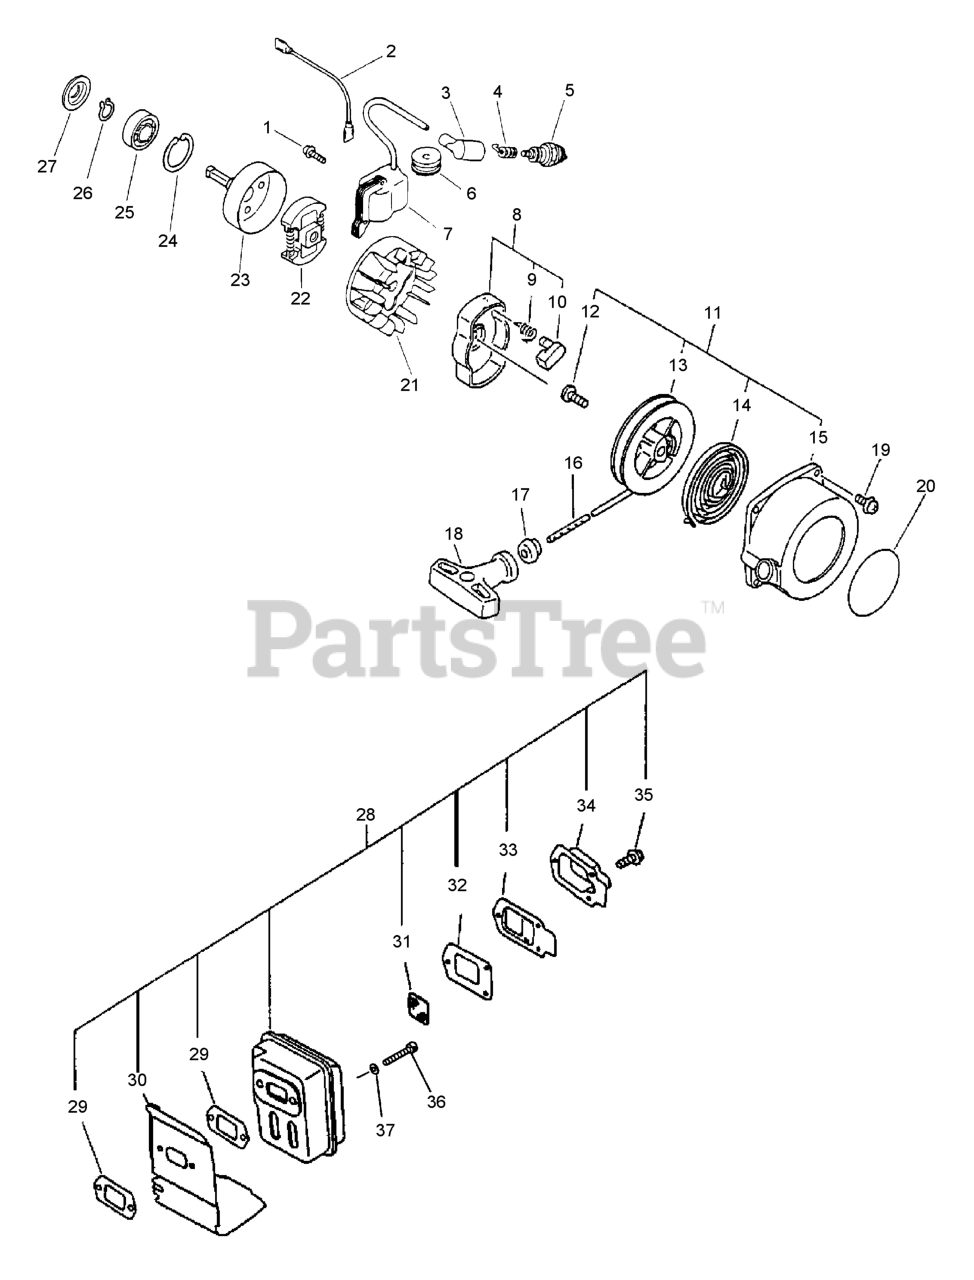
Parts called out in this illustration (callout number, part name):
1	SCREW 4x22
2	LEAD
3	CAP, SPARK PLUG
4	TERMINAL, SPARK PLUG
5	SPARK PLUG - BPM7A
5	SPARK PLUG - BPMR7A
6	GROMMET
7	COIL, IGNITION
8	PAWL ASSY, STARTER
9	SPRING, RETURN
10	PAWL, STARTER - BLACK
11	STARTER ASSY, RECOIL
13	REEL, ROPE
14	SPRING, RECOIL
15	CASE, RECOIL STARTER
16	ROPE, STARTER
17	GUIDE, ROPE
18	GRIP, STARTER
19	BOLT 4x16
20	LABEL - ECHO
21	FLYWHEEL
22	CLUTCH ASSY
23	DRUM, CLUTCH
24	RING, SNAP 32
25	BEARING, BALL 6201-ZZ
26	RING, SNAP 12
27	STOPPER
28	MUFFLER ASSY
29	GASKET, EXHAUST
30	COVER, EXHAUST
31	SCREEN, SPARK ARRESTER
32	GASKET, EXHAUST
33	GUIDE, EXHAUST
34	GUIDE, EXHAUST - INNER
35	SCREW 4x10
36	BOLT 5x55
37	WASHER, FLAT 5.5x10x0.8
